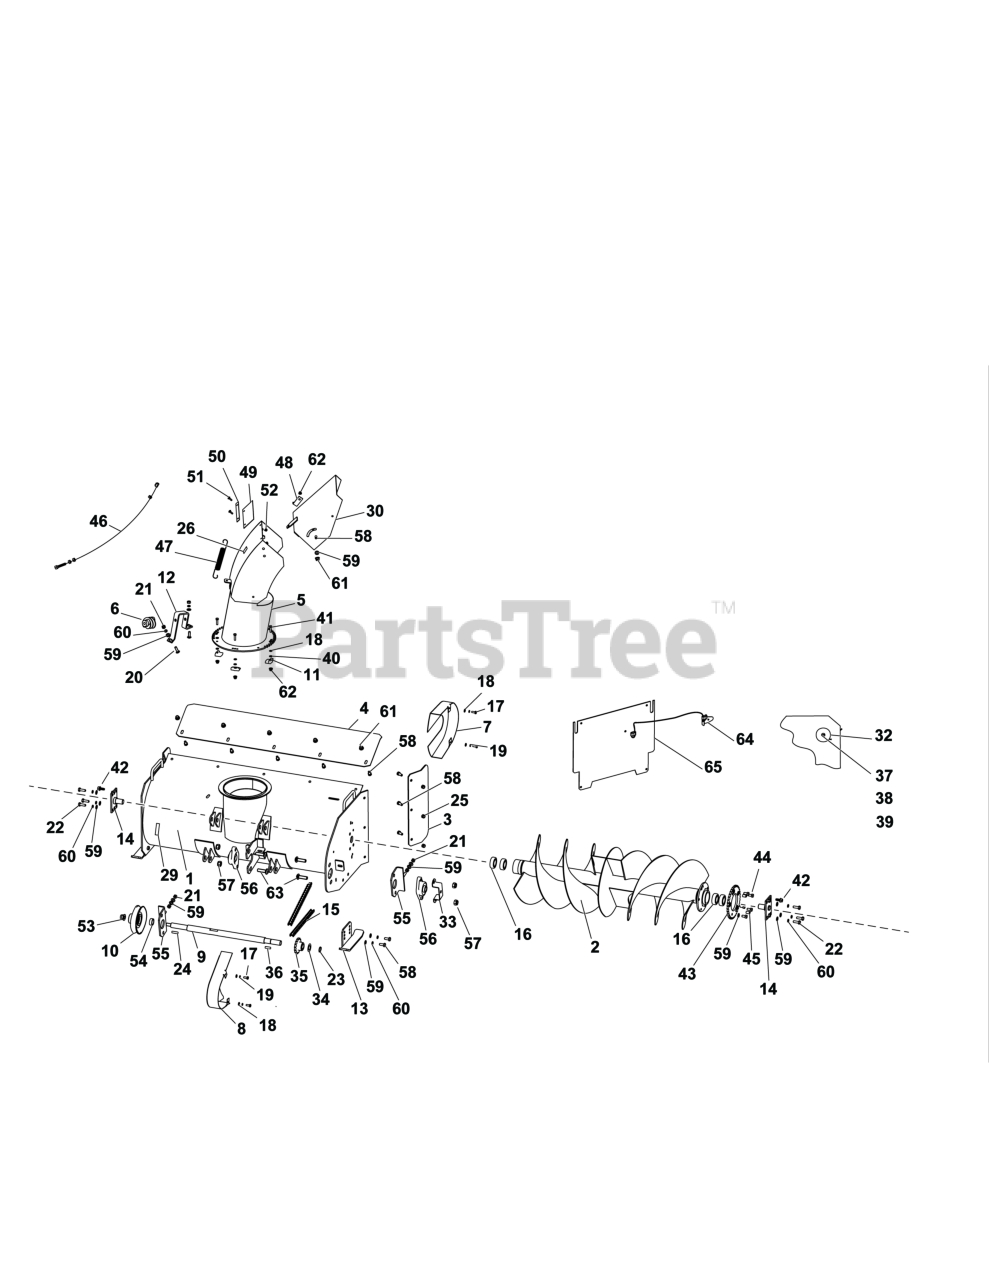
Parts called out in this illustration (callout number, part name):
23	RING, Locking
32	REFLECTOR
35	SPROCKET
43	SPROCKET
45	PIN, Shaft
46	CABLE, Control
55	STRAINER
